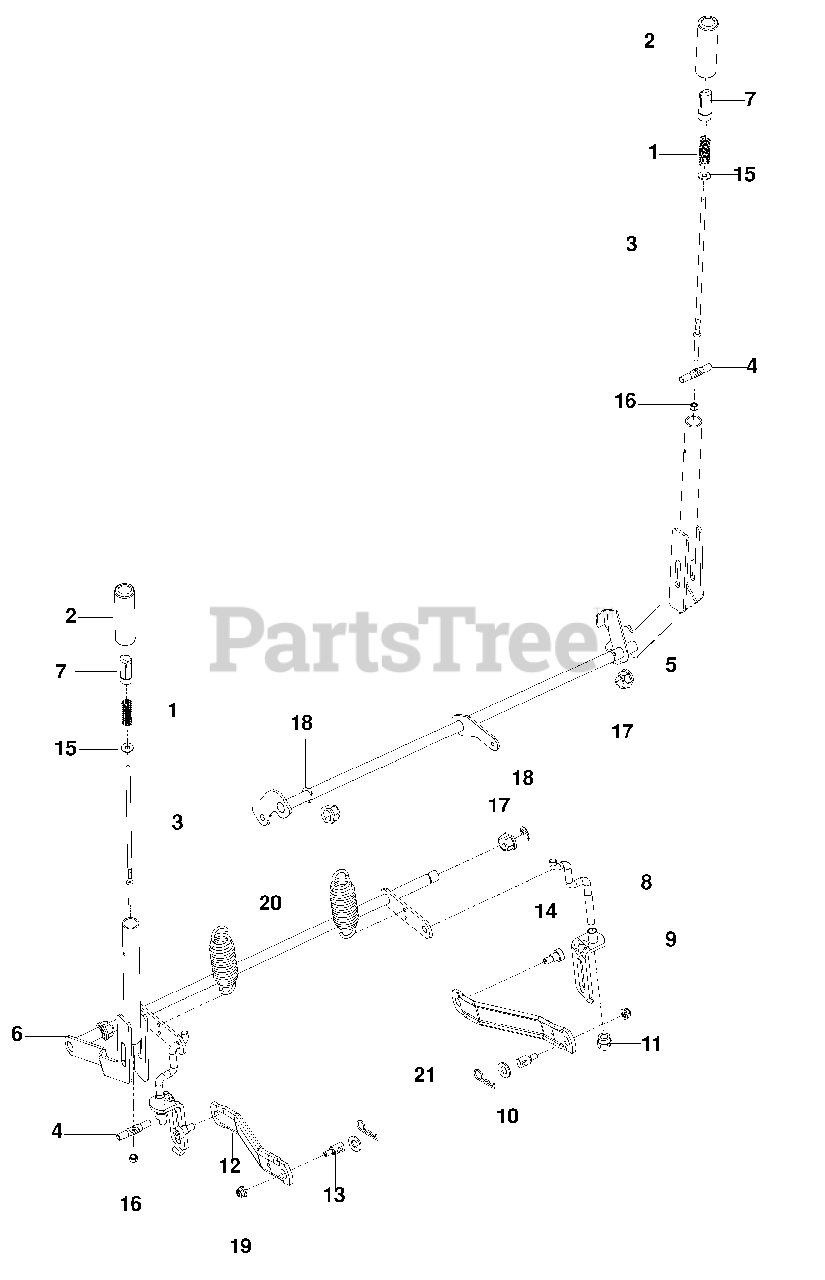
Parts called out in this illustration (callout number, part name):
1	SPRING, COMPRESSION
2	GRIP, HANDLE
3	ROD, HANDLE RELEASE
4	ROD, LATCH RELEASE
5	SHAFT, BRAKE
6	ARM, LIFTING
7	BUTTON, PUSH
8	LINK, REAR SUSPENSION
9	BRACKET, LIFT
10	WASHER 5/8 FLT SAE
11	NUT, LIFT LINK
12	ARM, SUSPENSION RR
13	STUD w/ ANTI-ROTATE
14	SB 3/8-16 x 3/8 SKT HD
15	WASHER 1/4 FLT
16	NUT 1/4-20 HEX NYLOC
19	NUT 5/16-18 FLANGE NYLOC
20	SPRING 965881301, 965881401, 966495701, 966514801
21	HAIRPIN #4
